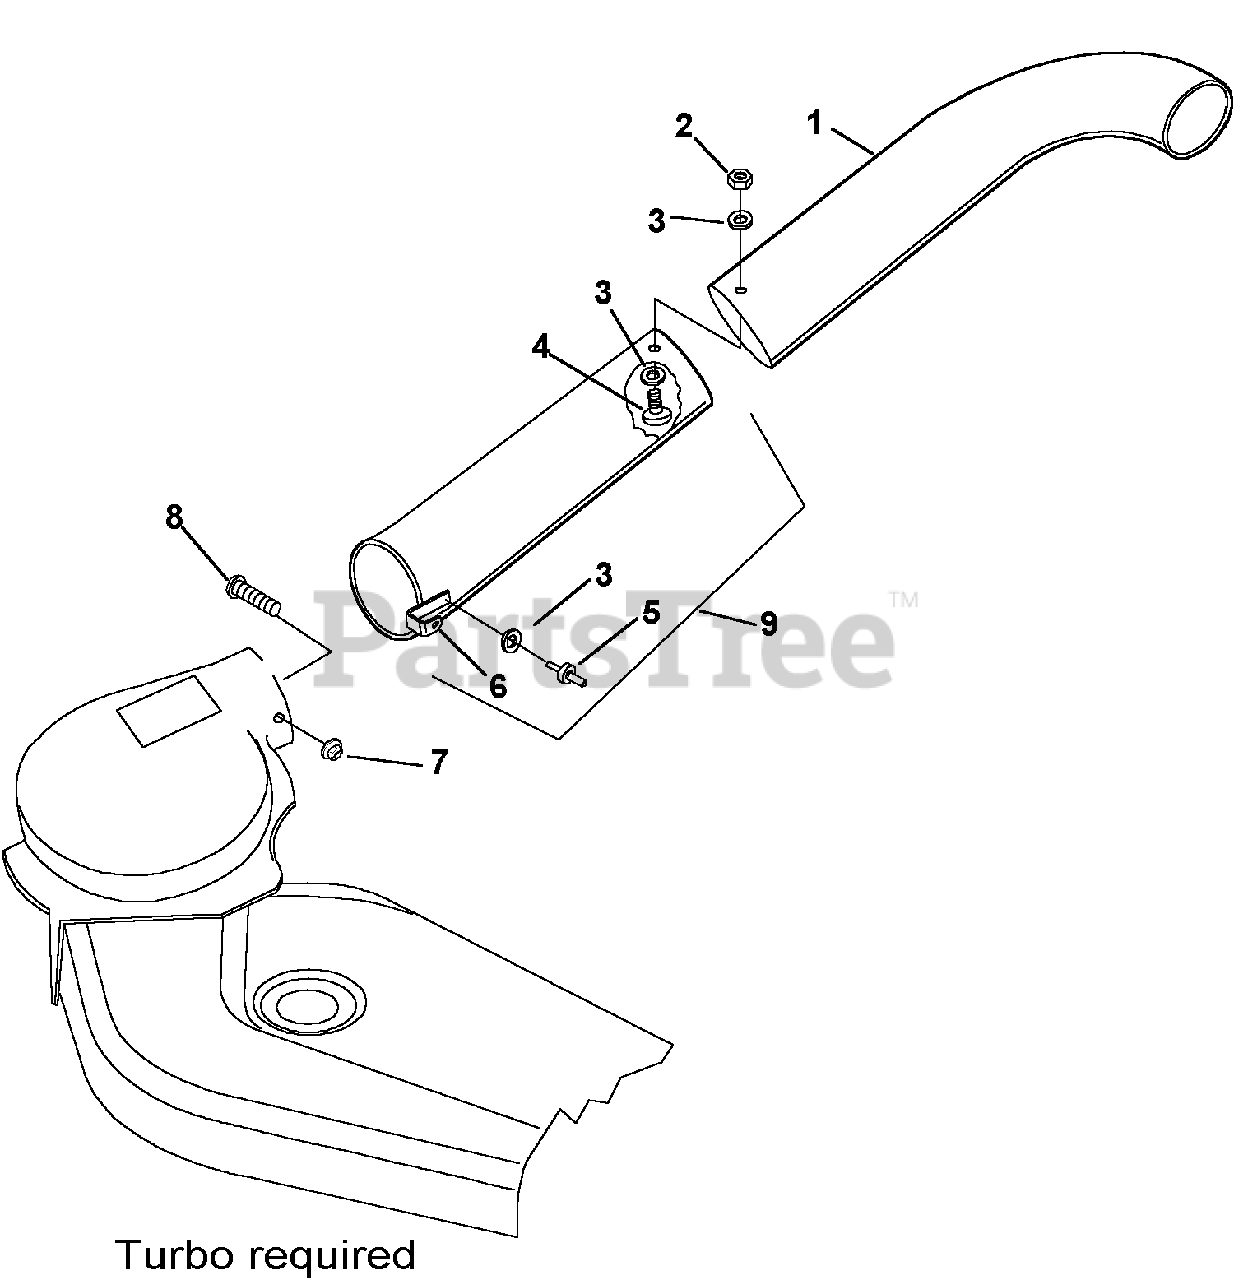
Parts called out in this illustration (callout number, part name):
1	ELBOW, Upper
2	NUT, Hex, Washer Assembly , #10-32
4	SCREW, Truss Head, #10-32 x 1/2
6	CLIP, Spring
7	CARRIAGE BOLT, 1/4-20 x 5/8
8	NUT, Hex Flange Lock, 1/4-20
9	TUBE & SPRING ASSEMBLY, (Incl. Ref. Nos. 3, 5 & 6)
